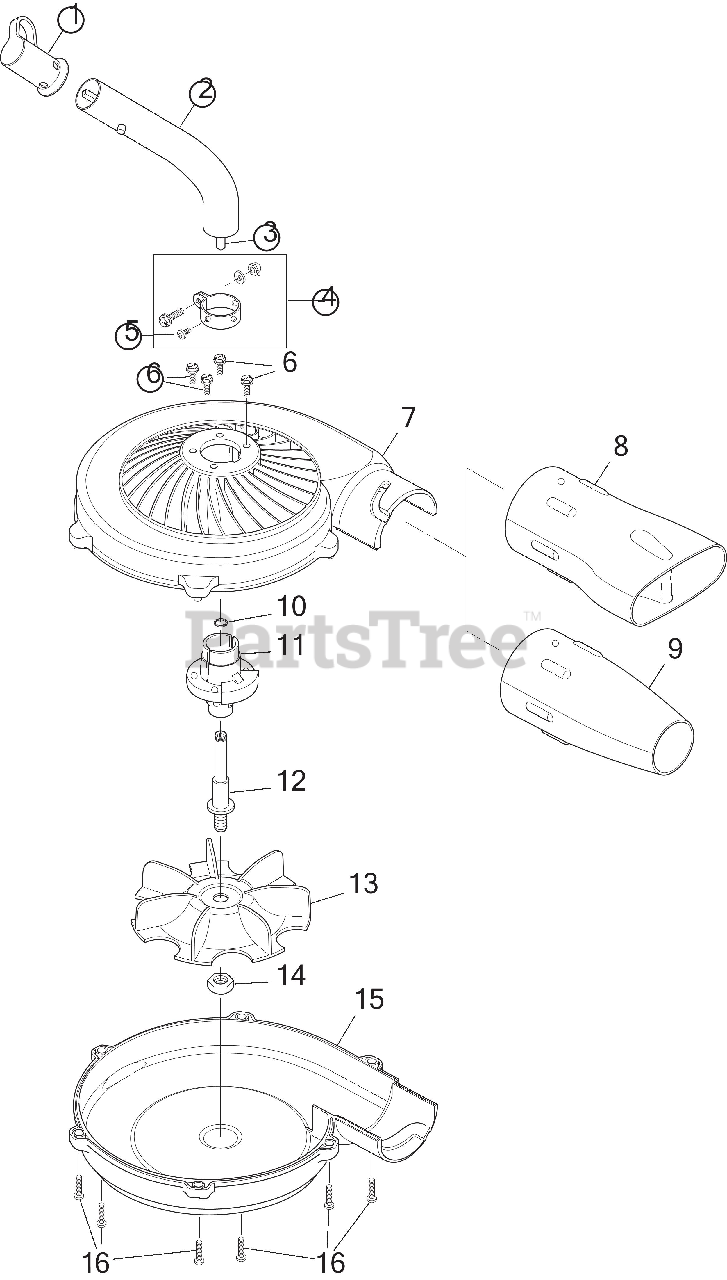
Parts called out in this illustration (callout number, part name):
1	HANGER
2	DRIVE SHAFT HOUSING ASSEMBLY
3	LOWERIBLE DRIVE SHAFT
4	CLAMP ASSEMBLY-LOWER
5	ANTI ROTATION SCREW
6	SCREW, 10-24X1/2 HEX
7	HOUSING, UPPER BLOWER AT
8	NOZZLE, SPREADER
9	NOZZLE, CONCENTRAT
10	PALNUT:3/8" DIAMET
11	ASSEMBLY, BUSHING HOUSING
12	SHAFT, DRIVE BLOWER
13	IMPELLER, BLOWER A
14	NUT, 7/16" THD, 3/
15	HOUSING, LOWER BLOWER AT
16	SCREW, #8-16X.750 PH
